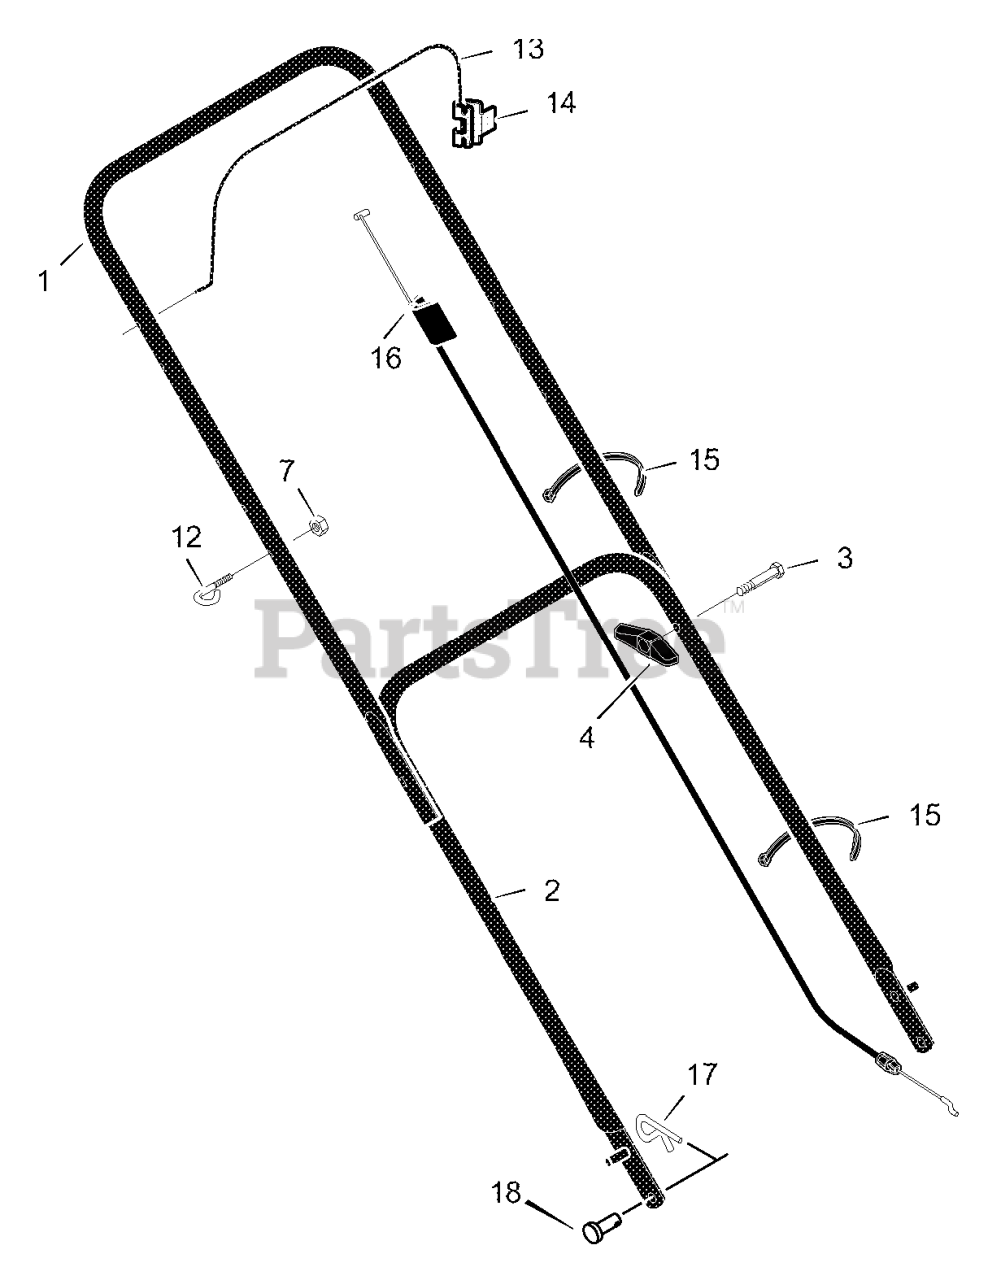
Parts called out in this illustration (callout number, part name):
1	Handle, Upper (Black)
2	Handle, Lower (Black)
4	Knob, Plastic
7	Locknut
12	Guide, Rope
13	Engine Stop Lever
14	Bracket, Stop Lever
15	Fastener, Cable
16	Engine Stop Cable
17	Pin, Hair
18	Pin, Clevis
